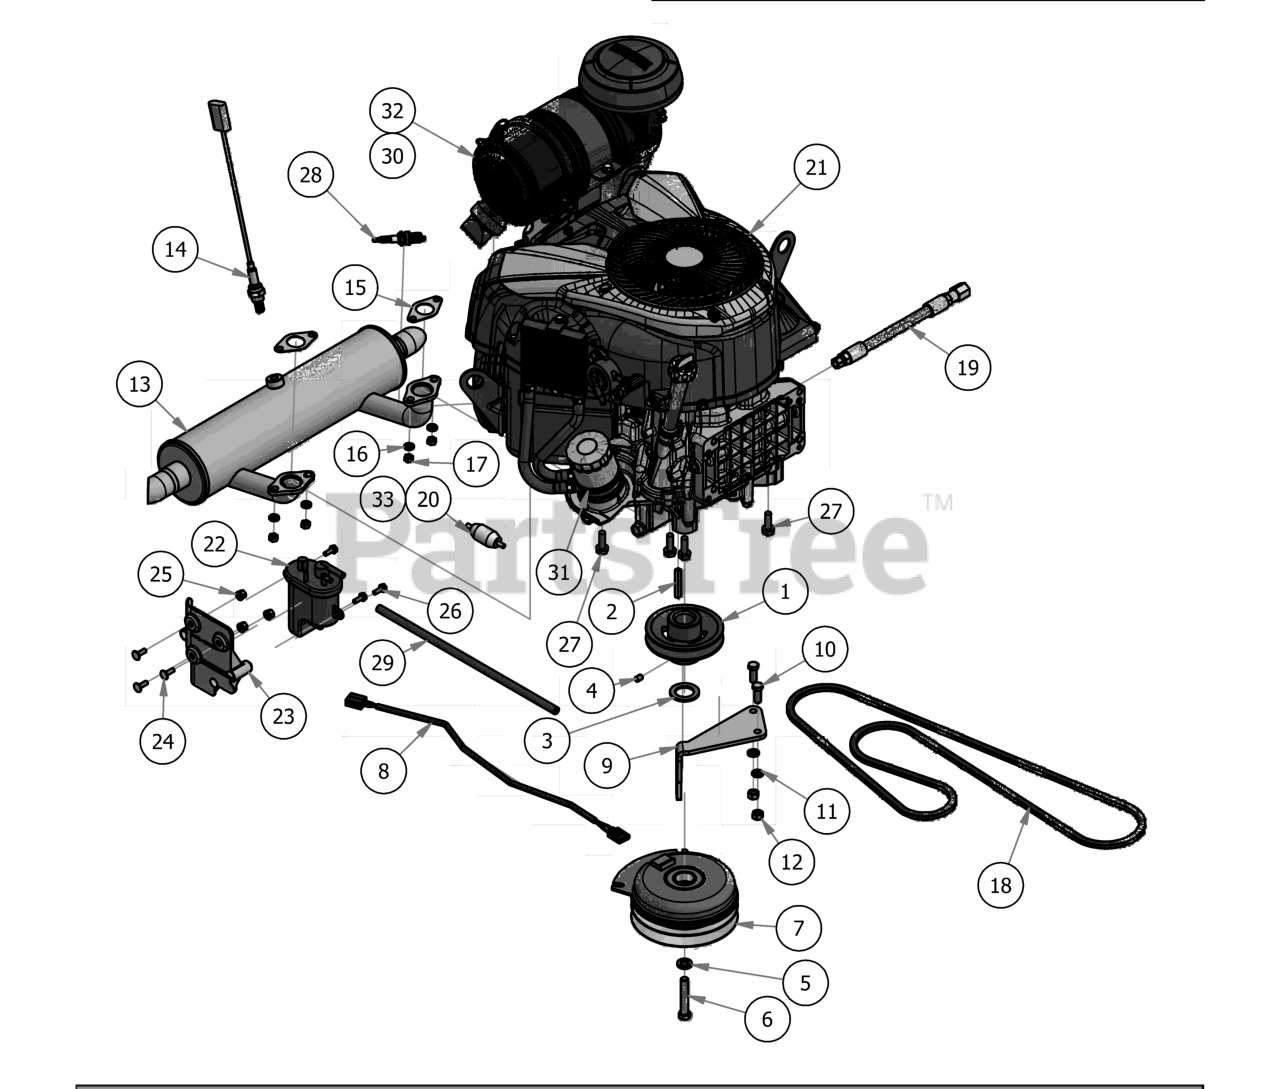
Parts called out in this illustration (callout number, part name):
1	4 3/4 Motor Pulley
2	1/4 x 2 Square key Stock
3	1 1/8" Flat Spacer
4	3/8" Set Screw
5	7/16" Lock Washer
6	7/16" x 2 1/2" Hex Bolt
7	Clutch Assembly
8	Clutch Pigtail
9	PTO Engager Holder
10	3/8" x 1" Hex Bolt
11	3/8" Lock Washer
12	3/8" Hex Nut
13	Yamaha Muffler
14	O2 Sensor for Yamaha
15	Exhaust Gasket for yamaha
16	5/16" Lock Washer
17	M8-1.25 Zinc Nut
18	Pump Belt Diesel
19	Oil drain Hose for Yamaha
20	Universal Inline Fuel Filter
21	Yamaha 33hp Engine
22	Yamaha Fuel Pump
23	Yamaha Fuel Pump Bracket
24	1/4" x 3/4" Carriage Bolt
25	1/4-20 Nylon Insert flange Nut
26	M6-1.0x16mm Washer Head Hex Bolt
27	3/8 x 1 1/8 bolt
28	Spark Plug - Yamaha
29	1/4 Fuel Line 15"
30	Canister Air Filter- Outer
31	Oil Filter
32	Canister Air Filter- Inner
33	Yamaha Fuel Filter
